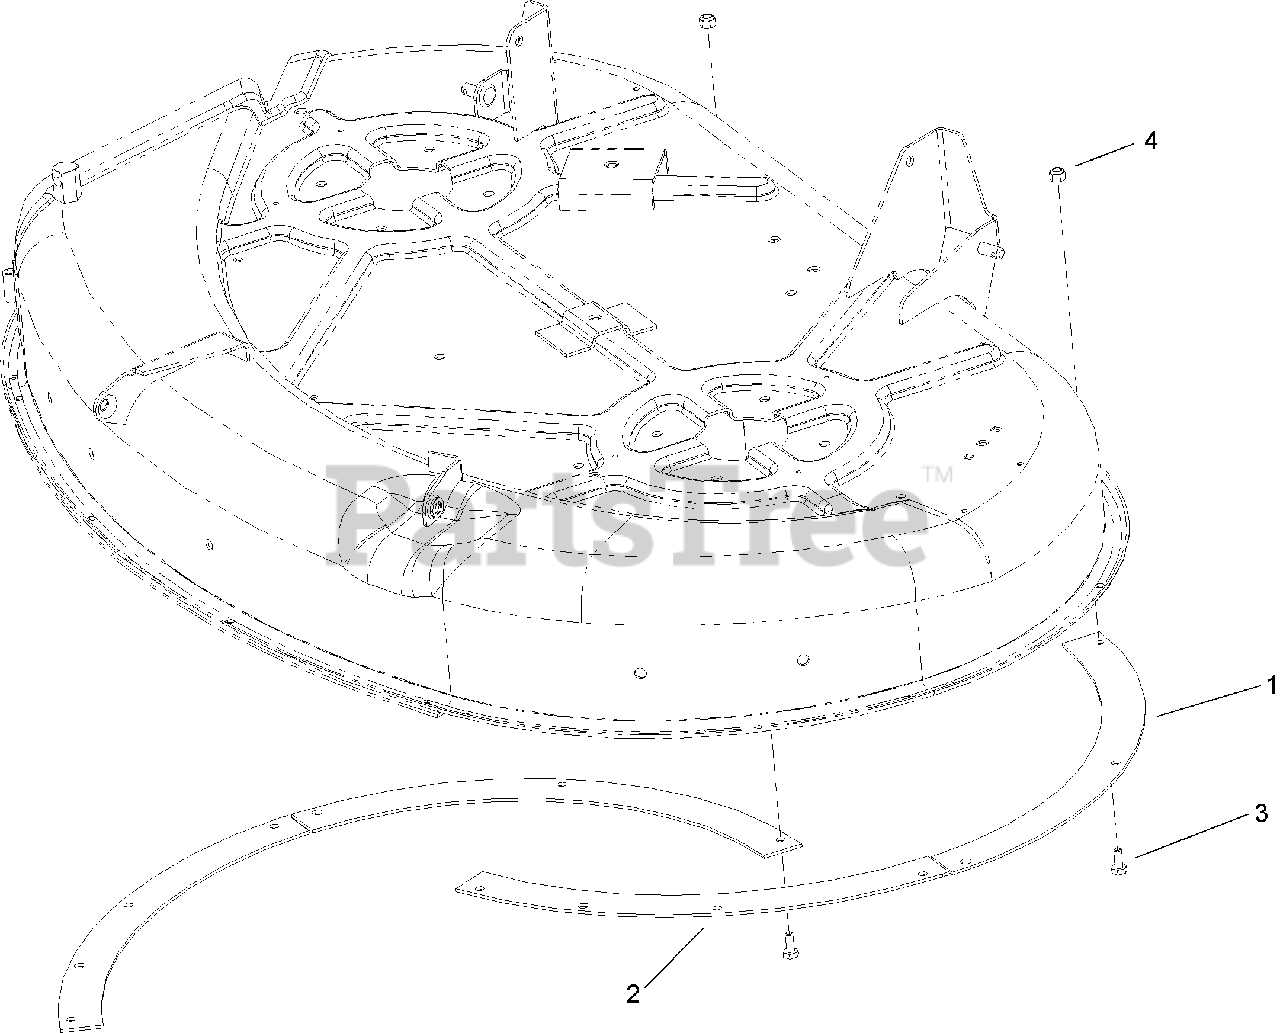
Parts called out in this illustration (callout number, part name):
1	RING-BLOW OUT, SIDE
2	RING-BLOW OUT, SIDE
3	SCREW-HH
4	NUT-LOCK, NI
